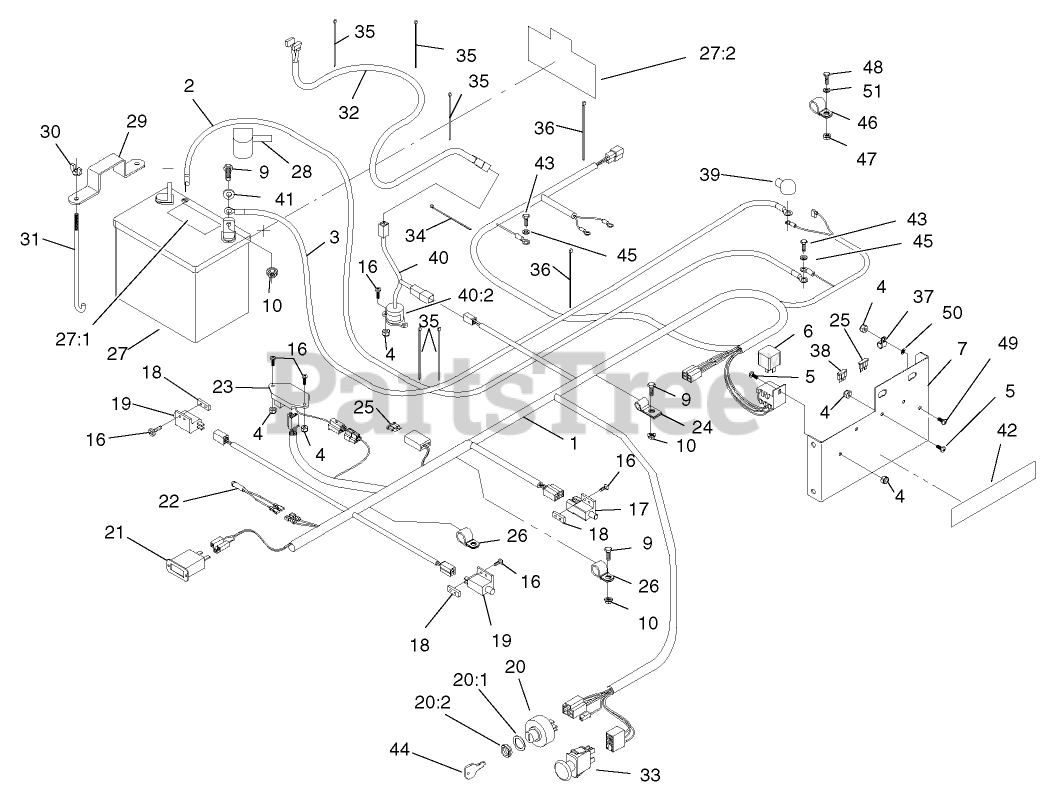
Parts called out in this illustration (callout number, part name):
1	HARNESS-WIRE
2	WIRE-GROUND
3	WIRE-BATTERY, POSITIVE
4	NUT-LOCK, NI
7	PANEL-MOUNT, FUSE
9	SCREW-HH
10	NUT-HF
16	SCREW-PPH
17	SWITCH
18	PLATE-TAPPED
19	SWITCH-OPEN, NORMALLY
20	Key Switch ASM
20:1	WASHER-TOOTH, INTERNAL
20:2	NUT-HH
21	METER-HOUR
22	INDICATOR-LED, RED
23	MODULE-DELAY, SEAT
24	CLIP-LOOM
25	FUSE-BLADE TYPE, 20 AMP
27	BATTERY
27:1	Decal-Battery
27:2	Decal-Battery
28	INSULATOR-BATTERY
29	STRAP-HOLDDOWN
30	WINGNUT
31	BOLT-HOLDDOWN
32	HARNESS-WIRING, SEAT
33	SWITCH-DELTA
34	TIE-CABLE
35	TIE-PLASTIC
36	TIE-PLASTIC
37	CLIP-LOOM
38	FUSE-BLADE TYPE, 10 AMP
39	INSULATOR-SOLENOID
40	TILT SWITCH ASM
40:2	DECAL-SWITCH, MERCURY
41	WASHER-FLAT
42	Decal-Fuse/Relay
43	SCREW-HH
44	KEY-IGNITION
45	WASHER-PLAIN
46	CLIP-LOOM
47	NUT-LOCK, NI
48	SCREW-HH
49	SCREW-HH
50	WASHER-FLAT
51	WASHER-FLAT
